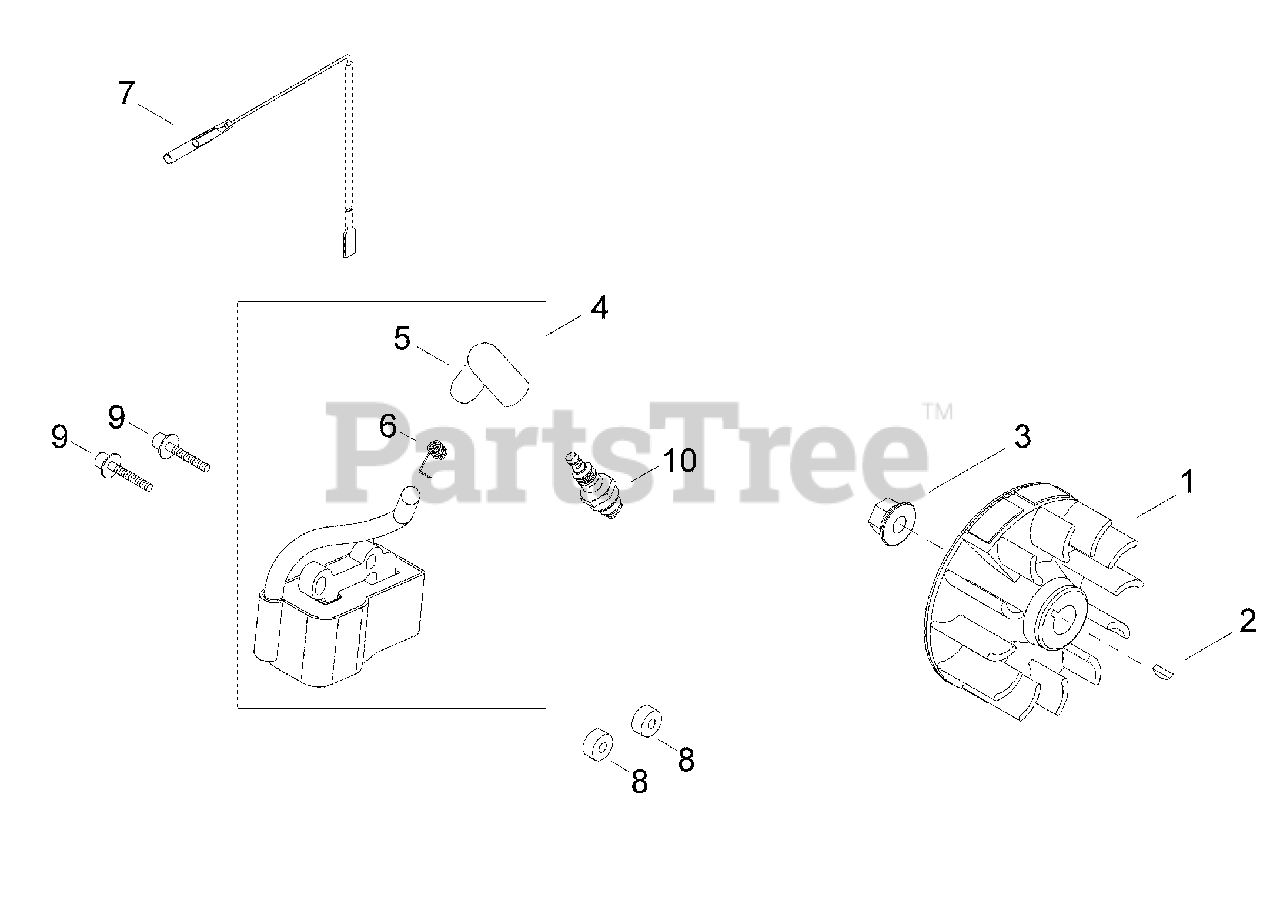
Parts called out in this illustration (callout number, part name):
1	FLYWHEEL
2	KEY - 3X10
3	NUT - 8
4	IGNITION COIL ASSY
5	CAP, SPARK PLUG
6	TERMINAL, SPARK PLUG CAP
7	LEAD - IGNITION
8	INSULATOR
9	SCREW - 4X26
10	SPARK PLUG -- CMR-5H
